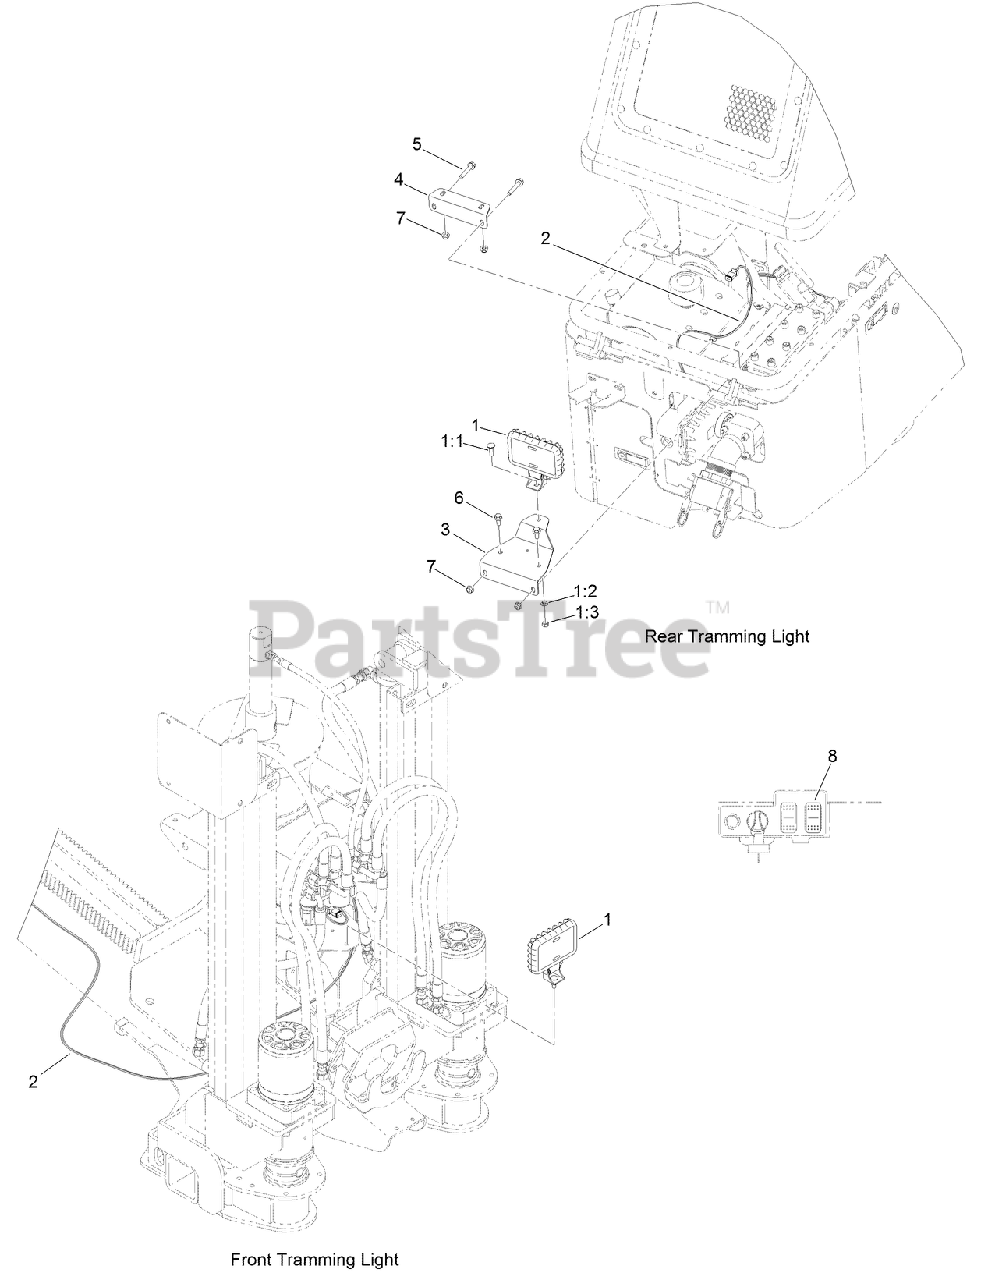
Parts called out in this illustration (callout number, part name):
1	LIGHT-WORK, LED
1:1	SCREW-CARR
1:2	WASHER-LOCK
1:3	NUT-HEX
2	HARNESS-WIRE
3	MOUNT-LIGHT, REAR
4	SUPPORT-MOUNT, LIGHT
5	SCREW-HWH
6	SCREW-HHF
7	NUT-HF, NI
8	SWITCH
